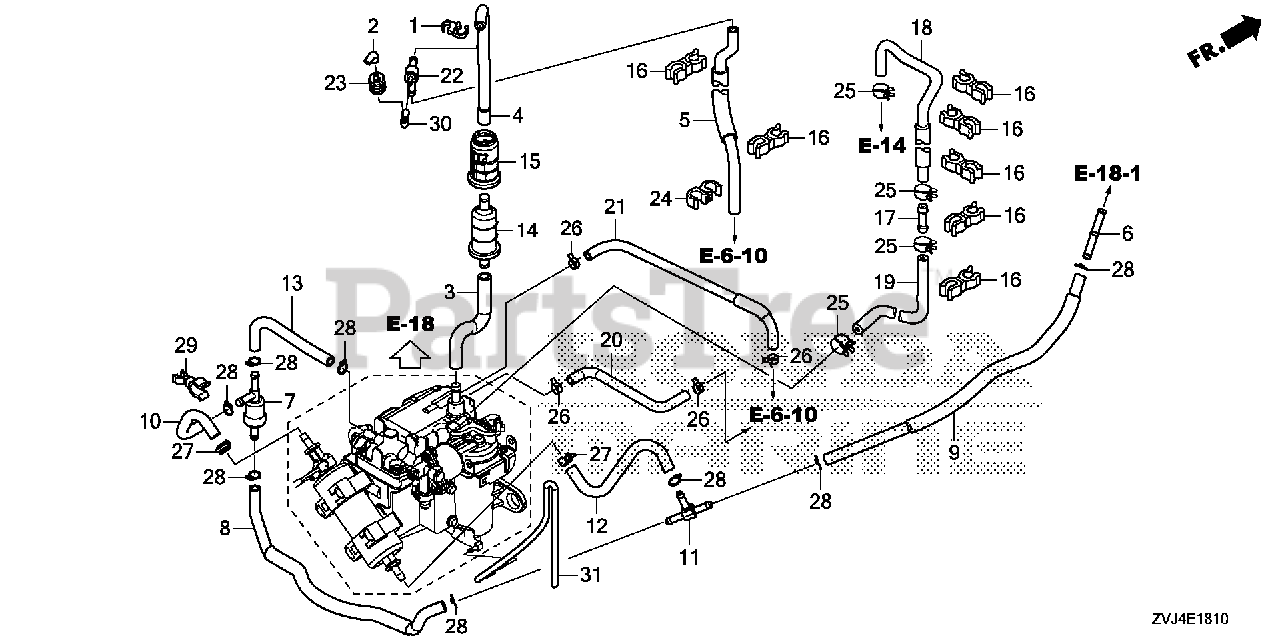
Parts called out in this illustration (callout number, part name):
1	CLAMP, CHECK VALVE
2	TUBE, CHECK VALVE
3	TUBE A, AIR VENT
4	TUBE B, AIR VENT
5	TUBE, AIR VENT
6	JOINT, FUEL FEED HOSE
7	VALVE, RELIEF
8	TUBE, RELIEF
9	TUBE C, FUEL
10	TUBE D, FUEL
11	JOINT, THREE WAY
12	TUBE E, FUEL
13	TUBE F, FUEL
14	FILTER, FUEL PUMP
15	SUSPENSION, STRAINER
16	CLAMP, HOSE
17	JOINT, FUEL RETURN
18	HOSE A, PRESSURE REGULATOR RETURN
19	HOSE B, PRESSURE REGULATOR RETURN
20	TUBE, WATER INLET
21	TUBE, WATER OUTLET
23	VALVE, CHECK
24	CLIP, SENSOR HOSE
25	CLAMP, TUBE (D10.7)
26	CLAMP, TUBE (D10.5) (ENGINE NO.)
27	CLAMP, TUBE (D12)
28	CLIP, TUBE (B12)
29	CLAMP (6MM-12MM)
30	BULK HOSE, FUEL (3.5X3000) (3.5X120)
31	BULK HOSE, VINYL (3.5X6.5X8000) (9500(95003-05001-60M) (CARBURETOR NO.)
